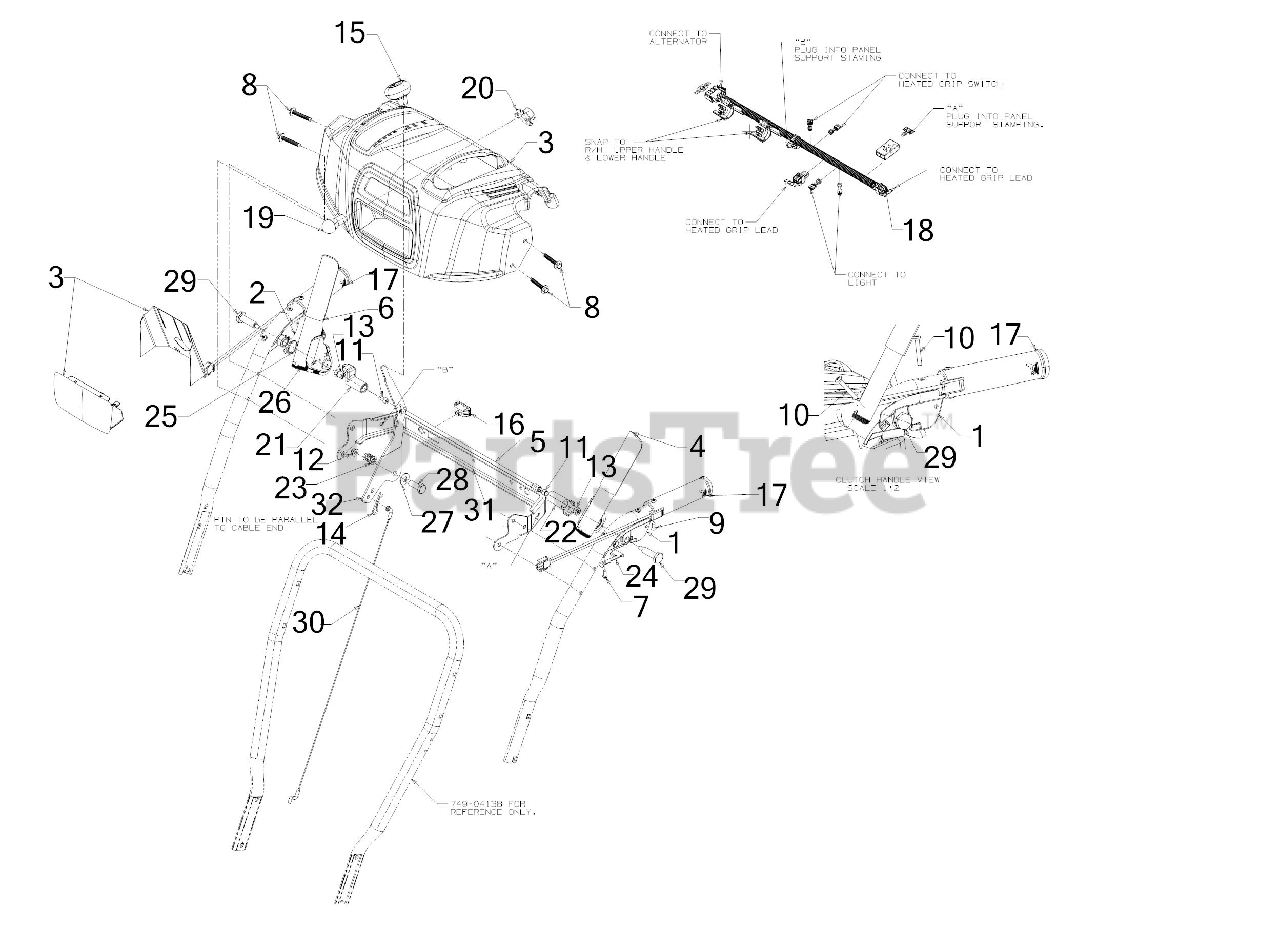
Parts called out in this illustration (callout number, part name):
1	CLUTCH LOCK HANLE ASSEMBLY (LH)
2	CLUTCH LOCK HANLE ASSEMBLY (RH)
3	HANDLE PANEL ASSEMBLY (CRAFTSMAN)
4	HANDLE ASSEMBLY (LH)
6	ENGAGEMENT HANDLE ASSEMBLY (RH) (BLACK)
7	SCREW #8-16 x .50
8	SCREW 1/4-20 x 1.625
9	SCREW #10-16 x .625
10	SCREW #10-24 x 1.375
11	SCREW 1/4-20 x .50
12	FLANGE LOCK NUT
13	HEX NUT W/PATCH
14	INTERNAL COTTER PIN
15	SHIFT KNOB
16	HEATED GRIP SWITCH
18	HEATED GRIPS HARNESS
20	HEADLIGHT SOCKET
22	CLUTCH LOCK CAM
23	COMPRESSION SPRING
24	CLUTCH SPRING
25	TORSION SPRING
26	RUBBER BUMPER
27	FLAT WASHER
28	SHOULDER SCREW
29	SHOULDER SCREW .437 x 1.345 1/4-20
30	SPEED SELECTOR CABLE (PLASTIC)
31	HANDLE SUPPORT BRACKET
